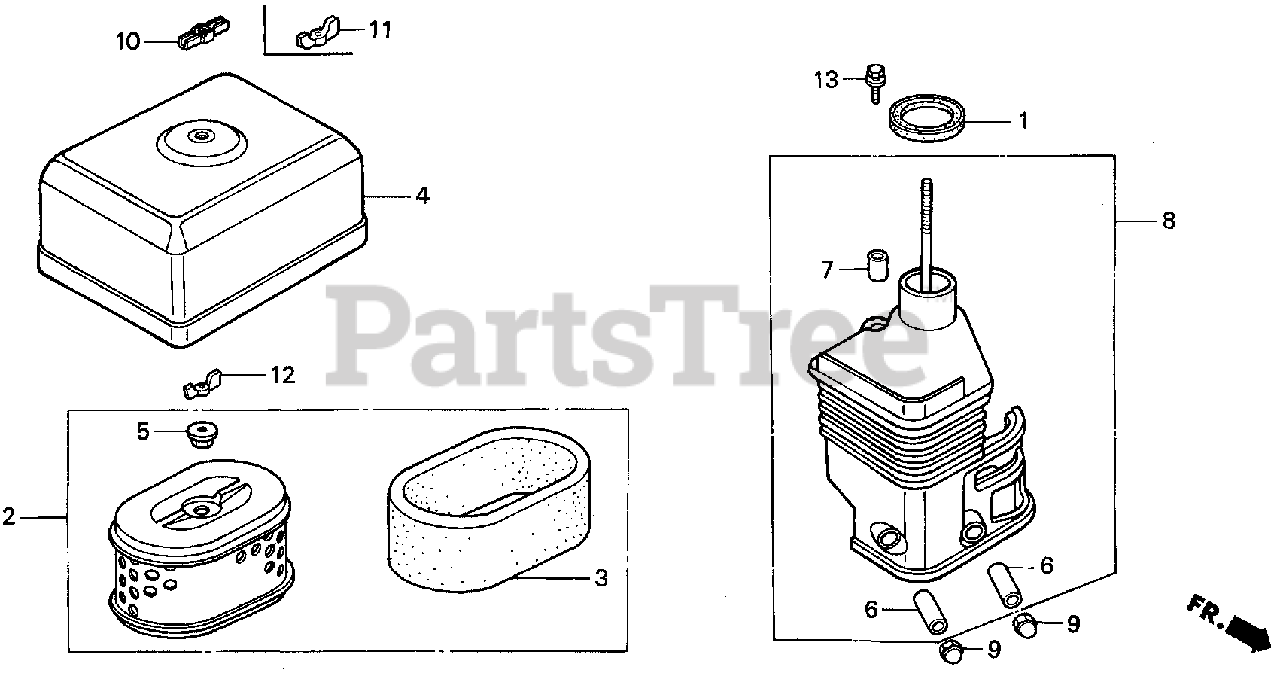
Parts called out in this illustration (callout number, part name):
1	GASKET, ELBOW
2	ELEMENT, AIR CLEANER (DUAL)
3	FILTER (OUTER)
4	COVER, AIR CLEANER (DUAL)
5	GROMMET, AIR CLEANER
6	COLLAR, AIR CLEANER
7	COLLAR B, AIR CLEANER
8	ELBOW, AIR CLEANER
9	NUT, CAP (6MM)
10	WINGNUT (6MM)
11	WINGNUT, TOOL BOX SETTING
12	WINGNUT, TOOL BOX SETTING
13	BOLT-WASHER (6X20)
13	BOLT, FLANGE (6X20)
